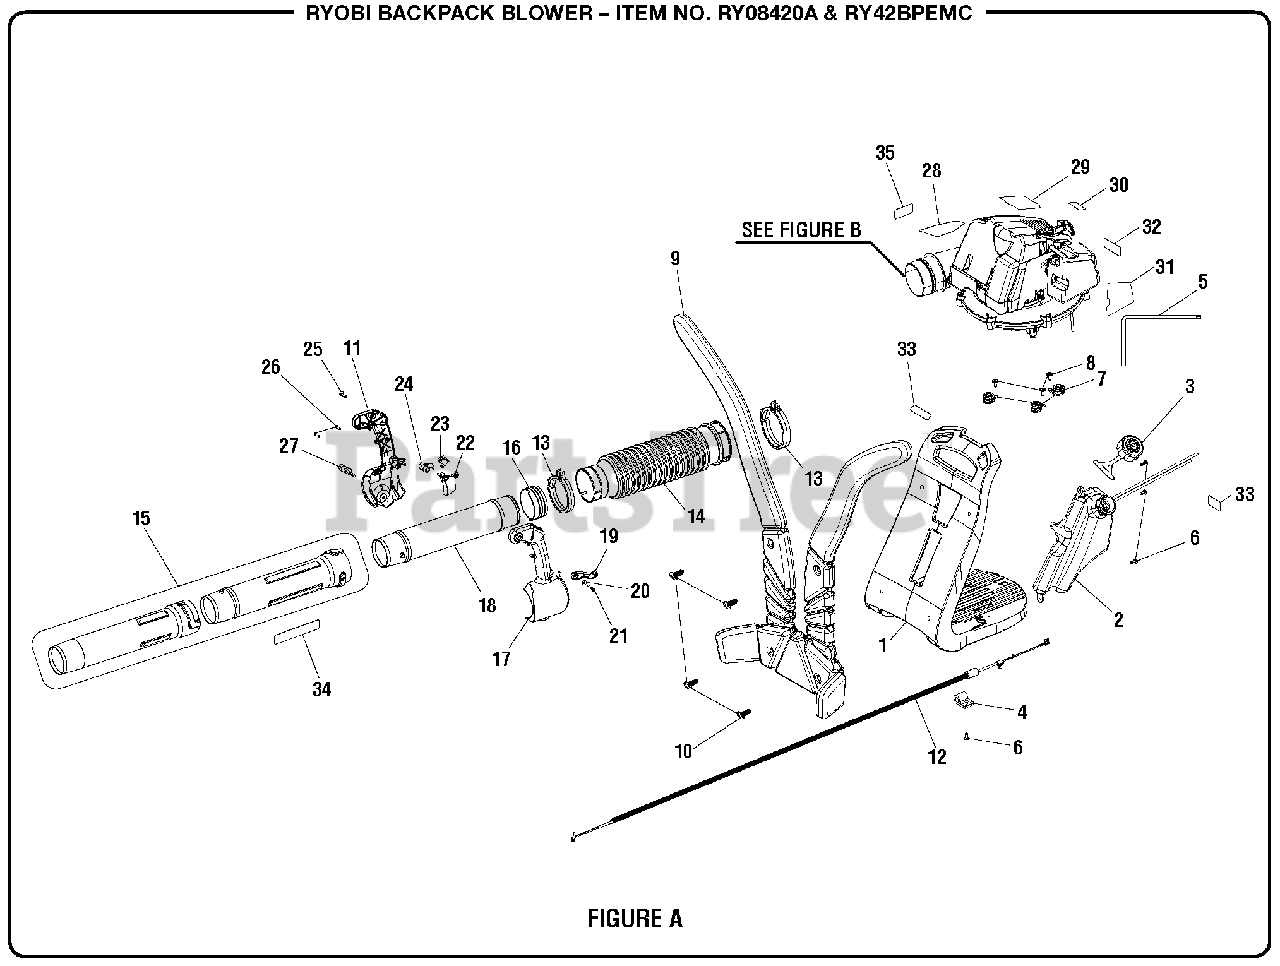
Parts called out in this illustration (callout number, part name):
1	Frame w/Labels
2	Fuel Tank Assembly w/Fuel Lines and Label
3	Fuel Cap Assembly w/Tether
4	Cable Clamp
5	Wrench (T-25)
6	Screw (10-14 x 14 mm)
8	Screw (10-14 x 16 mm)
10	Harness Snap Fastener
11	Right Hand Handle
12	Throttle Cable
13	Clamp Assembly Kit
15	Blower Tube Assembly
16	Upper Blower Tube Bushing
17	Left Hand Handle
18	Upper Tube
19	Cruise Lever
20	Washer (OD12 x ID4.3 x 1.5t)
21	Screw (8-14 x 25 mm)
23	Stop Switch
24	Trigger Lock
25	Screw (10-14 x 3/4 in.)
26	Screw (M4 x 16 mm, Pan Hd.)
28	Combustion Warning Label
29	Model Label
30	Choke Label
31	Start Instructions Label
32	Logo Label
33	Warning Label
34	Ryobi Tube Label
35	EMC Label (RY42BPEMC)
